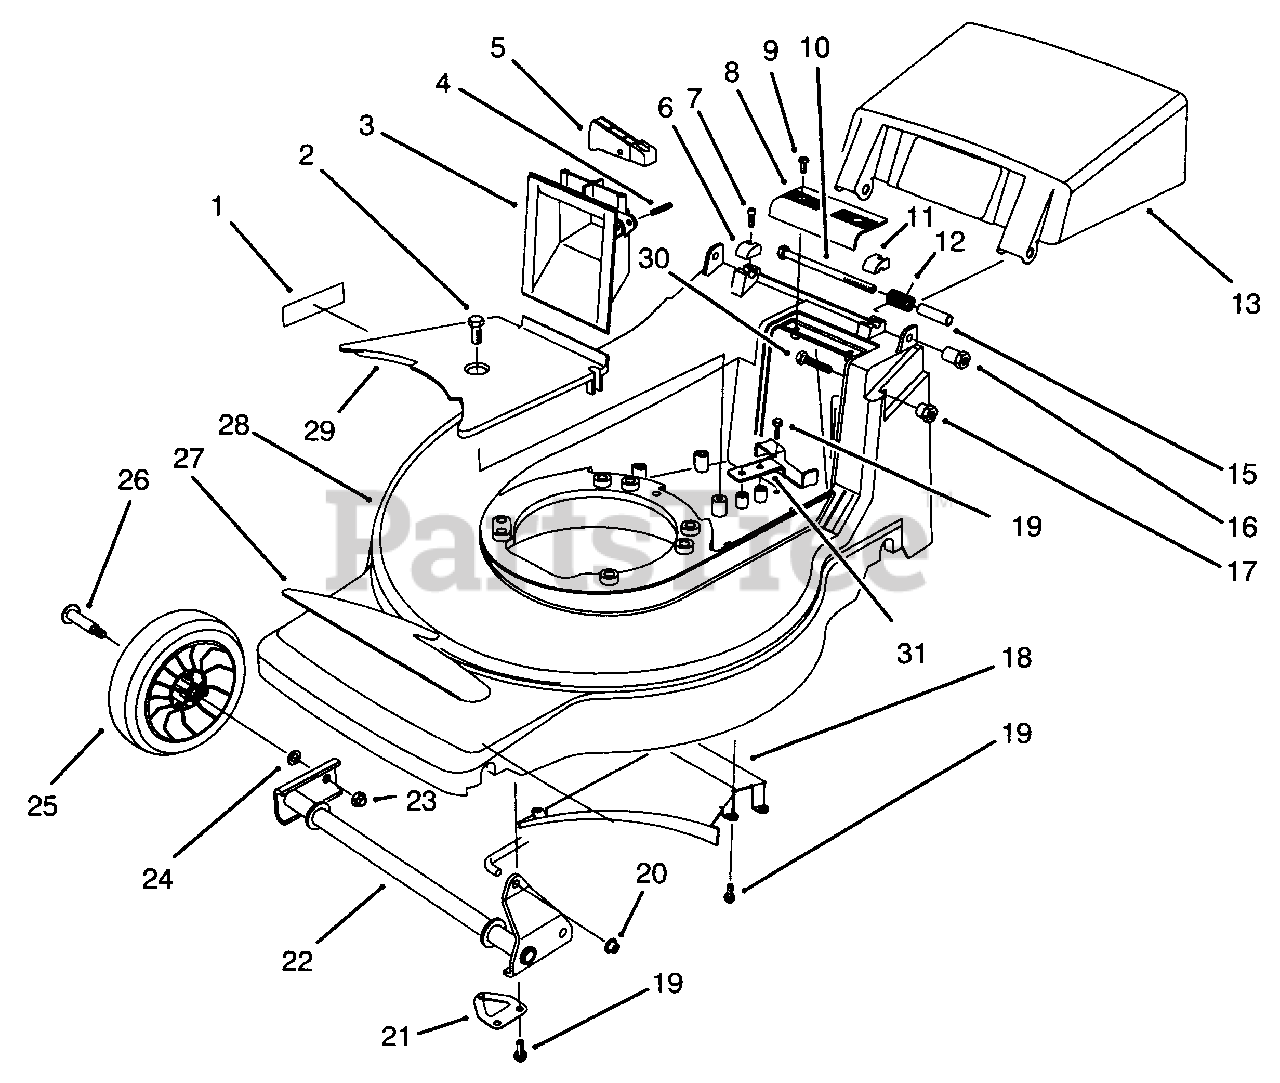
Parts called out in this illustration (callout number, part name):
1	Decal-Danger
2	Screw-Tapping
3	Grip-Lower
4	Pin-Groove
5	Trigger-HOC
6	Cap-R.H. Hinge Bolt
7	Screw-Thread Forming
8	Grip-Upper
9	Screw-Pan Hd. Phillips
10	Screw-Hex Hd. Cap
11	Cap-L.H. Hinge Bolt
12	Spring-Door
13	Door-Discharge
15	Spacer-Door
16	Spacer-Handle
17	Spacer-Handle
18	Ramp-Discharge
19	Screw-Tapping
20	Nut-Push
21	Retainer-Shaft
22	Pivot-Front
23	Nut-Lock
25	Wheel & Tire Assembly
26	Bolt-Wheel
27	Decal-Deck 400XS
28	Housing (Incl. Ref. #1)
29	Cover-Belt
30	Screw-Hex Hd. Cap
31	Guide-Rear Belt
